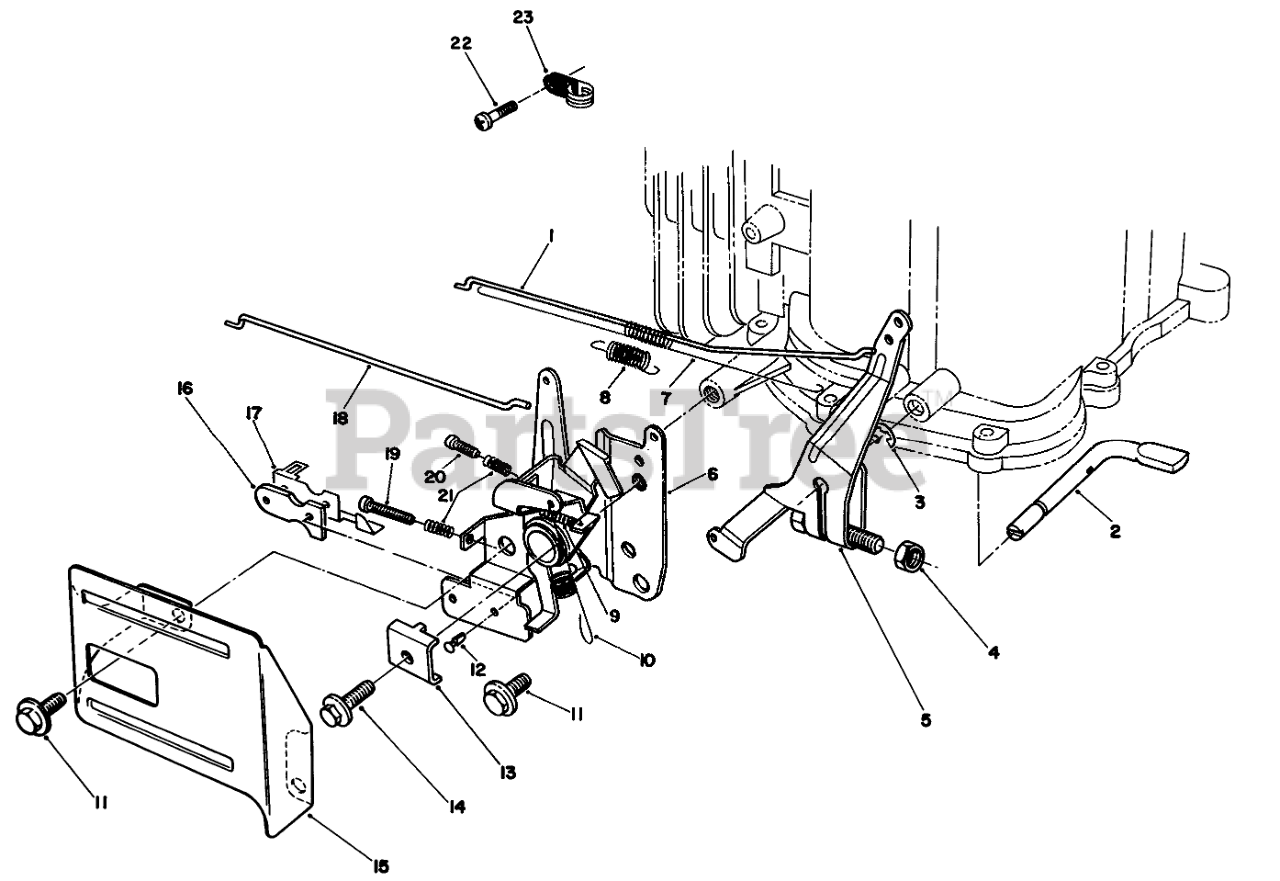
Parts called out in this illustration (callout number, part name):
1	Rod-Carburetor
2	SHAFT
3	E-RING
4	Nut
5	ARM ASM
6	THROTTLE
7	SPRING
8	SPRING
9	SPRING
10	SPRING
12	RIVET
13	CLAMP-CABLE
15	THROTTLE GUARD
16	INSULATOR-KILL SWITCH
17	TERMINAL-KILL SWITCH
18	Rod-Choke
19	SCREW
20	SCREW
21	SPRING
22	SCREW
23	Clamp
